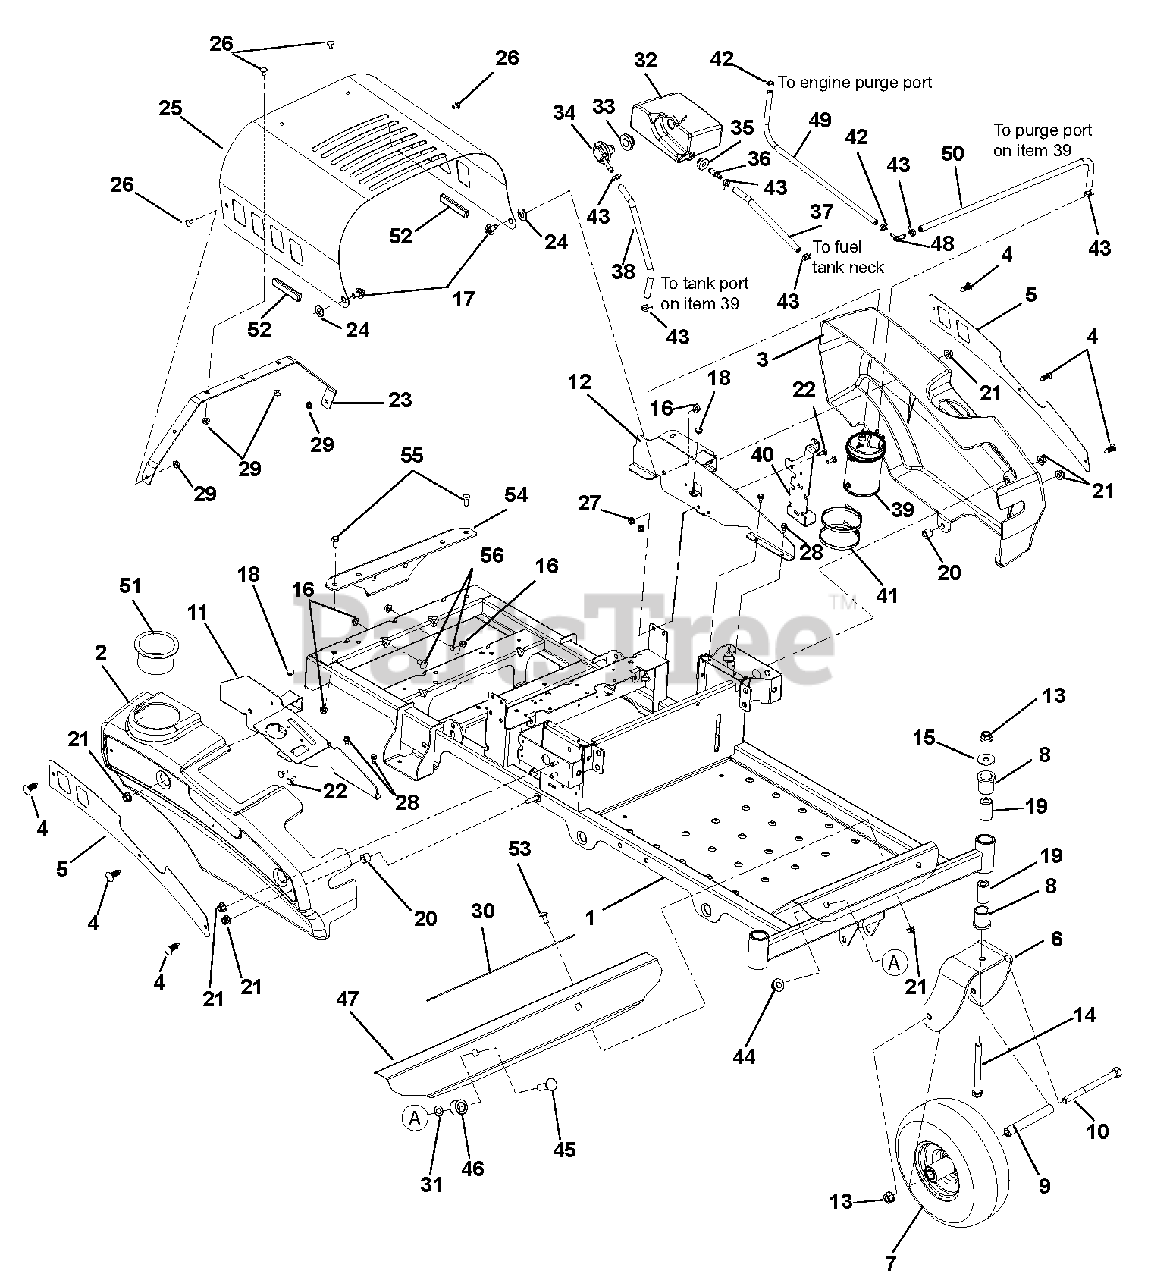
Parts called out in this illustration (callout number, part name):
1	Weldment, Frame
2	Fender, Right Hand
3	Fender, Left Hand
4	Rivet, Nylon
5	Plate, Fender
6	Fork, Caster
7	Wheel/Tire Assembly, 11 x 4-5
8	Bushing, Flange 1.00 x 1.25 x 1.50 x 1.50
9	Spacer, Wheel
10	Bolt, Hex .50-13 x 6.50
11	Weldment, Fender Mount Right Hand (915170)
12	Weldment, Fender Mount Left Hand
13	Nut, Locking Top Flange .50-13
14	Bolt, Hex .50-13 x 5.00
15	Washer, Flat Steel .511 x 1.441 x .125
16	Nut, Locking Top Flange .38-16
17	Bolt, Shoulder .375-16 x .135
18	Bumper Grommet .125 x .250 Diameter
19	Spacer, Caster
20	Bushing, Sleeve .391 x .688 x .52
21	Nut, .31-18 Nyloc Flange
22	Bolt, Round Head Square Neck .25-20 x .75
23	Hood Brace
24	Washer, Flat Nylon .52 x 1.00 x .08
25	Hood, Zoom
26	Bolt, Round Head Square Neck .25-20 x .50
27	Nut, .25-20 Nyloc Flange
28	Screw, Tapping .25-20 x .50 Hex Washer Head Thread
29	Nut, Locking Top Flange .25-20
30	Grip, Adhesive (1" x 16" BLK)
31	Nut, Push .50
32	Tank, ZT/Waw Fuel Exp.
33	Grommet, Remote Vent Nitrile
34	Vent, Roll-Over (.25" ID Hose)
35	Bushing, Flange .375 x 1.062 x .625 R
36	Fitting, Straight Fuel
37	Hose, .25 Low-Perm Bulk Gas
38	Hose, .25 Low-Perm Bulk Gas
39	Carbon Canister, 300CC
40	Bracket, Mount, Canister BBZ
41	Plastic Tie Strap Large
42	Clamp, Hose Spring .188
43	Clamp, Hose Wire .490/.510 x .116
44	Nut, Locking Nylon Flange .50-13
45	Bolt, Round Head Square Neck .50-13 x 1.75
46	Tube, Upper Control Pivot
47	Foot Rest
48	Fitting, 3/16 x 1/4 90 Deg Vac
49	Hose, .188 Low Perm Bulk (915168)
50	Hose, .25 Low Perm Bulk Gas (915168)
51	Cupholder
52	Edging, Clutch Paddle – 2.00"
53	Bolt, Round Head Square Neck .31-18 x .75
54	Plate, BBZ Hitch Kit Plate (915170)
55	Bolt, Hex .38-16 x .75 (915170)
56	Bolt, Round Head Square Neck .31-16 x .75 (915170)
